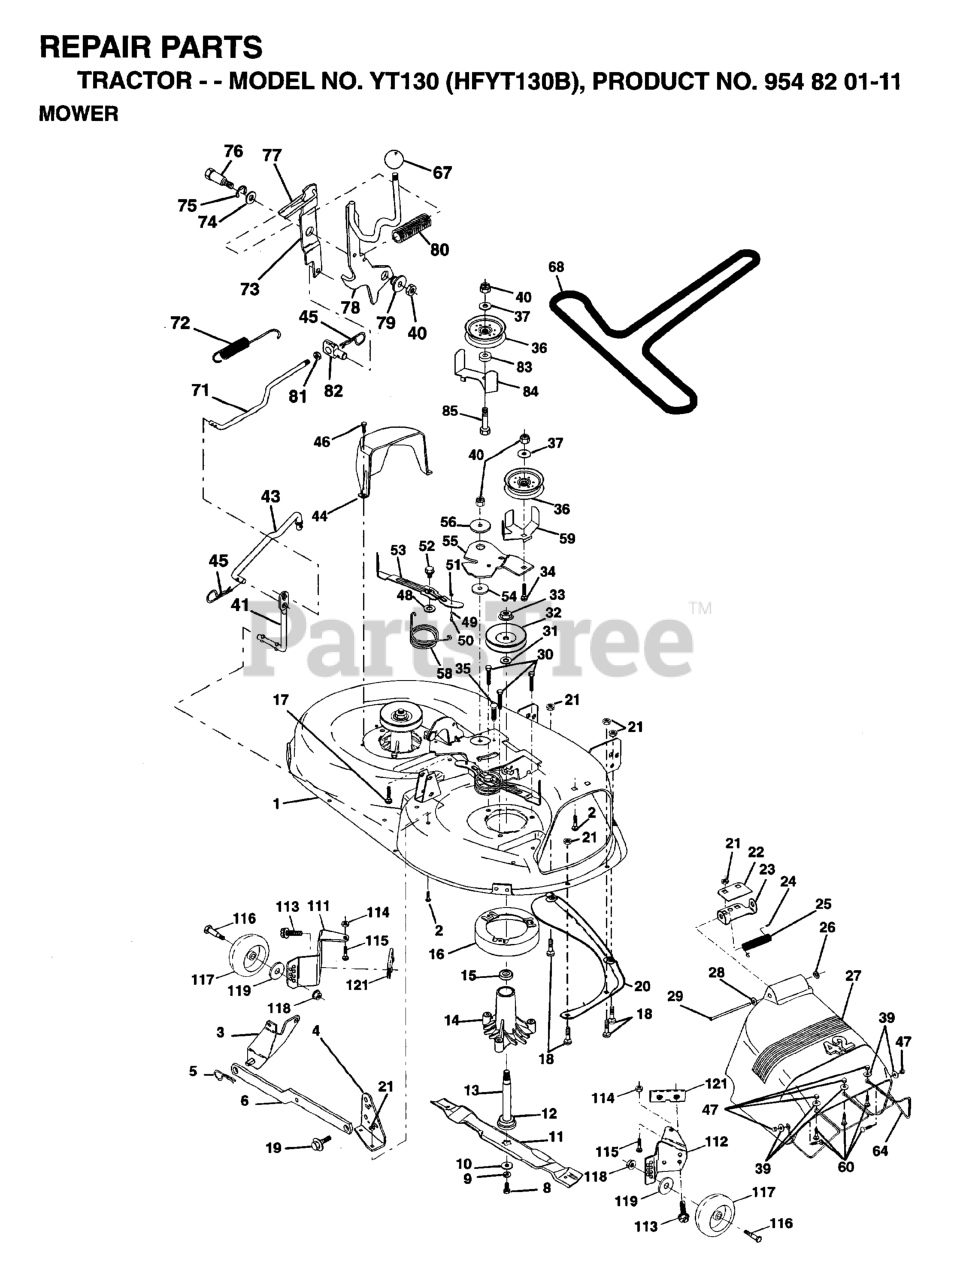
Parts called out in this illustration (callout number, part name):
1	DECK 42"
2	RP BOLT 5/16-18 X3/4 ZN/YEL GR
3	BRKT ASM SWAY BAR
4	BRKT DECK SW BAR
5	RETAINER-SPRNG RB
6	REAR SUSP ARM
8	BLADE BOLT
9	LOCKWASHER
10	WASHER.BLADE
11	Blade Mower 42" High Perf.
12	BEARING.BALL.#6204.(MANDREL)
13	SHAFT ASM VENT
14	HOUSING.MANDREL.VENTED (MACHD)
16	STRIPPER
17	BOLT
18	BOLT
19	BOLT SHD 5/16-18
20	BAFFLE
21	LOCKNUT
22	STIFFENER BRACKET
23	DEFLECTOR BRACKET
24	CAP-SLEEVE LT
25	SPRING TORSION
26	NUT PUSH M
28	Washer 11/32 x 5/8 x 16 Ga SD
29	ROD.HINGE
30	SCREW
31	WASHER
32	MANDREL PULLEY
33	NUT
35	FASTENER.XMAS.TREE
36	FLAT IDLER PULLEY
37	WASHER
39	REPL BY 734 11 46-01
43	CLUTCH ROD
44	GUARD MANDREL LH BLACK
45	RETAINER M
46	SCREW.1/4-20X5/8
47	NUT
49	CAM FOLLOWER
52	BOLT.SHOULDER.5/16-18
53	ARM
54	HARDENED WASHER
55	IDLER ARM
56	SPACER RETAINER
59	GUARD, BELT
60	SCREW
67	KNOB T (1/2-HOLE)
68	V-BELT TRIPATH
71	CLUTCH ROD
72	RETURN SPRING
73	ARM CLUTCH SECONDARY
77	KEEPER SPRING
78	CLUTCH ARM
79	BUSHING.FLANGE.E-RING.GROOVE
80	SPRING
81	NUT
82	TRUNNION.ADJUSTABLE.3/8-16
84	KEEPER BELT
85	BOLT
111	BRACKET
112	BRACKET
113	SCREW.THDROL.5/16-18X3/4.TTY
114	NUT
115	BOLT.CARR.5/16-18X1/2
116	BOLT, SHOULDER
117	WHEEL GAGE DONUT
118	LOCKNUT
119	WASHER.5/16.FLAT.STE.STD.
121	BRACKET.EXTRUDED.GAGE.WHEEL
